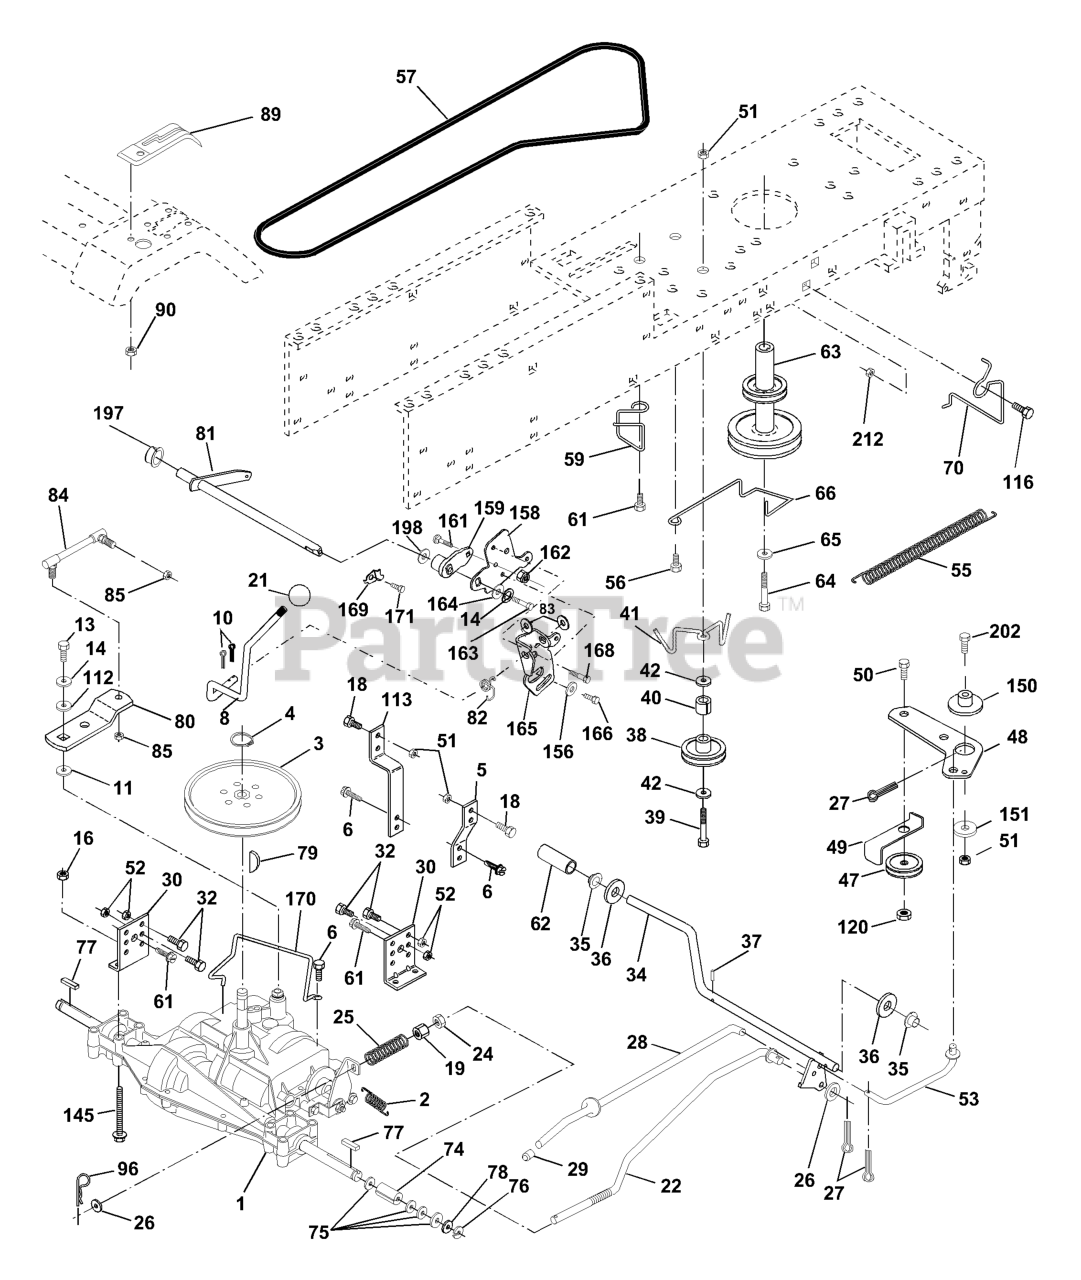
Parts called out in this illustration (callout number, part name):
2	SPRING,BRAKE RETURN
3	PULLEY TRANS
4	RETAINING RING LT
5	STRAP TORQUE
6	SCREW 5/16"
8	ROD.SHIFT.FENDER.ADJ.LT.CRD
10	PIN COTTER
11	WASH-SHFT PLT LT
13	BOLT 1/4-28X3/4
14	LOCKWASHER
16	NUT.71038.31-18.HEX.NYLOCK
18	BOLT
19	NUT
21	KNOB T (1/2-HOLE)
24	NUT
25	SPRING ROD LT
26	WASHER
27	COTTER PIN
28	ROD, PARKING BRAKE
29	PLUNGER CAP
30	BRKT, MOUNT TRNSAXLE
32	BOLT
34	SHAFT, FOOT PEDAL
35	BEARING.NYLON
36	WASHER LT
37	DRIVE PIN
38	PULLEY.FLAT
39	BOLT
40	SPACER, SPLIT
41	KEEPER, BELT IDLER
42	WASHER
47	IDLER PULLEY
48	BELLCRANK, CLUTCH
49	RETAIN BELT
50	BOLT
52	LOCKNUT
53	LINK, CLUTCH LT
55	SPRING, RETURN LT
56	SCREW THDROL 3/8-16 X 1-1/2
57	V-BELT
59	KEEPER, BELT CENTER
61	SCREW 3/8-16X3/4
62	PEDAL COVER T
63	ENGINE PULLEY
64	BOLT
65	LOCKWASHER
66	KEEPER BELT ENGINE
70	KEEPER BELT ENG
74	SPACER AXLE
77	SQUARE KEY
79	KEY STD (1373) DANA
81	SHAFT ASM CROSS TAPERED
82	SPRING,TORSION
83	WASHER
84	LINK.TRNSAXLE
85	NUT LOCK CENTER 1/4 -28 FNTHD
89	CONSOLE, SHIFT STLT
90	NUT.PUSH.3/16
96	RETAINER M
112	WASHER LT
113	STRAP TORQUE LH LT
116	BOLT D
120	NUT LOCK FLG 3/8-16 UNC
145	BOLT
150	SPACER, RETAINER
151	WASHER 12/32X2X10GA
156	WASHER.SRRTD.5/16
158	BRACKET
159	HUB
161	BOLT
162	NUT.CROWNLOCK.1/4
163	BOLT
164	Washer5/8 x .281 x 10 Ga
165	RP BRACKET
168	BOLT.SHOULDER.5/16-18X
169	PLATE FASTENING LT
170	Keeper Belt T/A
171	SCREW LT
197	NYLINER SNAP 5/8" ID
198	WASHER.NYL.7/8IDX.105"HYD CR
212	NUT
